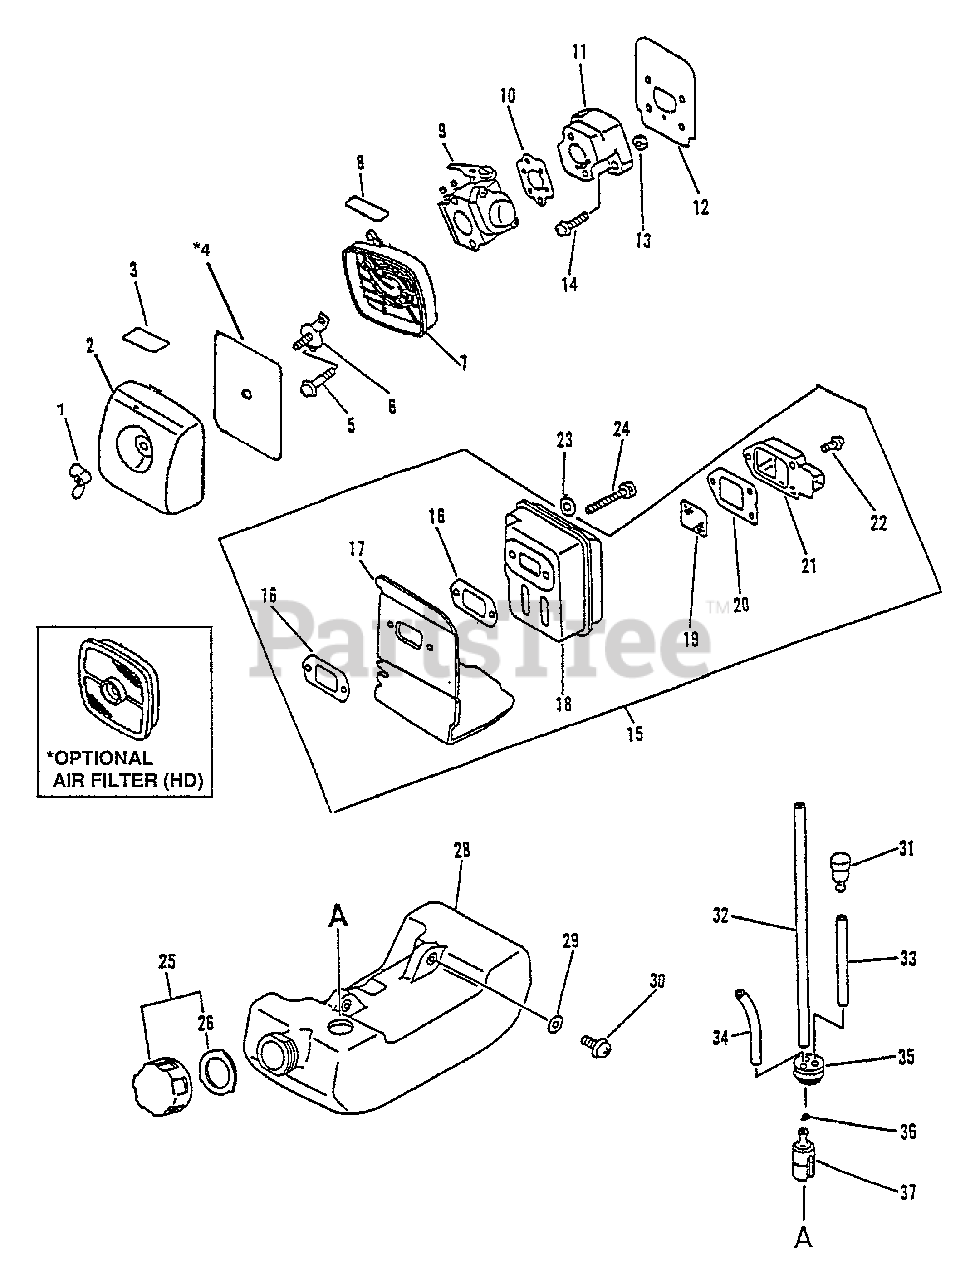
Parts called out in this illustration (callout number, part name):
1	WINGNUT - 6
2	COVER, AIR FILTER
3	LABEL - TOP
4	FILTER, AIR
5	SCREW 5×64
6	PLATE, PREVENT
7	AIR FILTER CASE ASSY
8	LABEL, CHOKE
9	CARBURETOR - C1U-K29
10	GASKET, INTAKE
11	INSULATOR, INTAKE
12	HEAT SHIELD, INTAKE
13	NUT M5
14	SCREW 5×20
15	MUFFLER ASSY
16	GASKET, EXHAUST
17	COVER, EXHAUST
19	SCREEN, SPARK ARRESTER
20	GASKET, EXHAUST
21	GUIDE, EXHAUST - INNER
22	SCREW 4×10
23	WASHER, FLAT 5.5×10×0.8
24	BOLT 5×55
25	CAP ASSY
26	GASKET, FUEL CAP
28	TANK, FUEL
29	WASHER 5.5×12×0.8
30	SCREW 5×16
31	VENT ASSY
32	PIPE, FUEL 3x-5x-180
33	PIPE, FUEL 3x-5x-70 BLACK
34	PIPE, FUEL 3×6×80 CLEAR
35	GROMMET, FUEL
36	CLIP 6 MM
37	FILTER, FUEL
